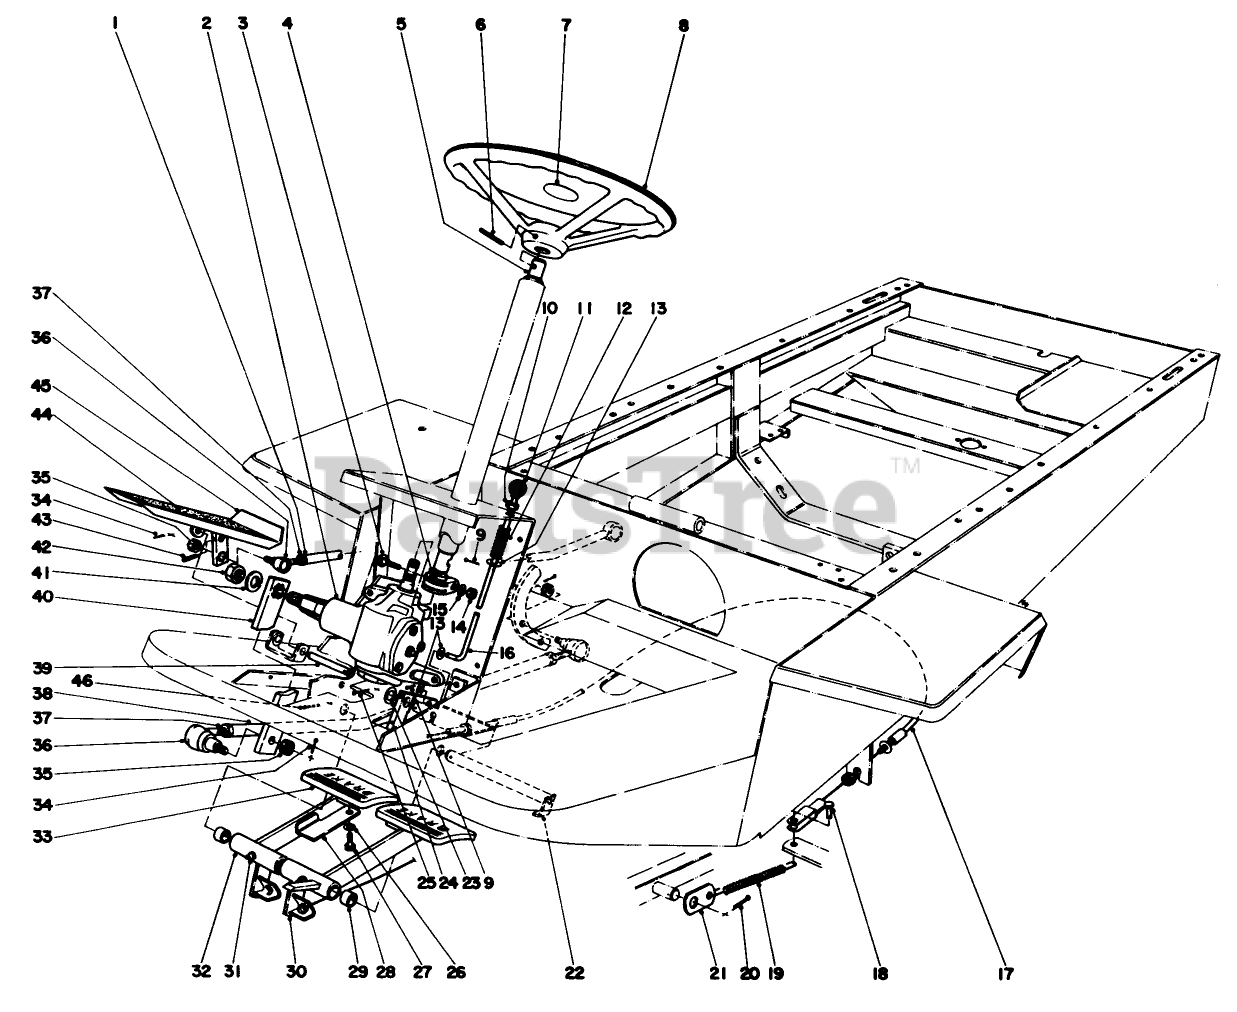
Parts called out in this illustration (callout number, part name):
1	PUMP CONTROL TUBE WA
2	Steering Gear
3	SCREW-CARR
4	CLAMP STRG COUPLING
5	Steering Shaft
6	PIN-ROLL
7	STEERING WHEEL CAP
8	STEERING WHEEL
9	PIN-COTTER
10	NUT-HEX
12	Spring
13	WASHER-FLAT
14	NUT-HEX
15	WASHER-LOCK
16	Rod Brake Latch
17	RH BRAKE CABLE ASM
18	PIN-CLEVIS
19	SPRING-EXTENSION
20	PIN-COTTER
21	BRAKE SPRNG STRAP R
23	WASHER-FLAT
24	RACK WA
25	PIN-COTTER
26	WASHER-LOCK
27	SCREW-HH
28	Latch Parking Brake
29	BUSHING
30	Brake Pedal L.H. (Incl. Ref. #29 & 31)
31	FITTING-GREASE
32	Brake Pedal R.H. (Incl. Ref. #29 & 31)
33	PAD-BRAKE
34	PIN-COTTER
35	NUT-SLOTTED
36	Socket Assembly (Incl. Ref. #35)
37	NUT-JAM
38	FRONT STEERING TUBE B
39	Pin Traction Pedal
40	Arm Gear Box
41	WASHER-LOCK
42	NUT-JAM
43	PIN-ROLL, SLOT
44	Non Skid Pedal
45	Pedal
46	PIN-COTTER
